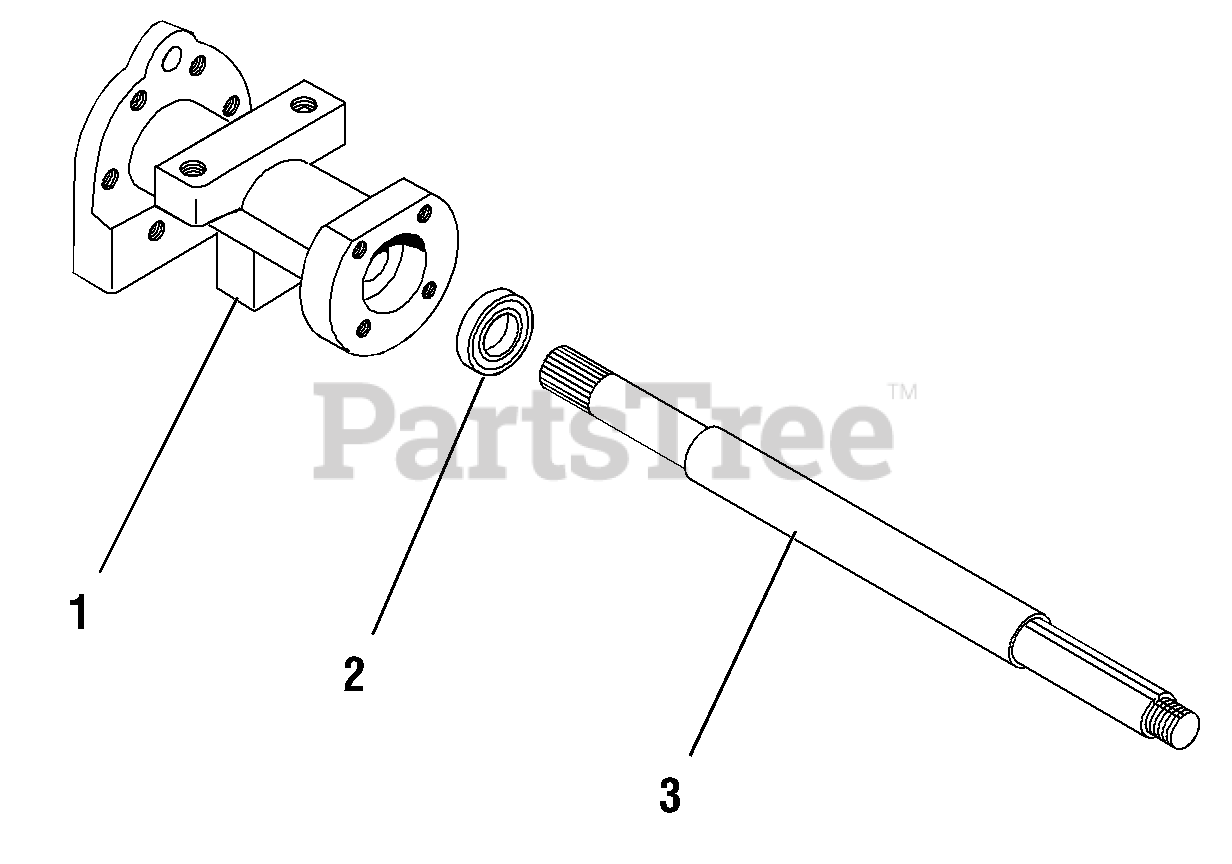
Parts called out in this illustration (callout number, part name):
1	HOUSING, Axle, 8-3/8" Long
2	BEARING, Ball
3	AXLE, 16-9/16" Long
